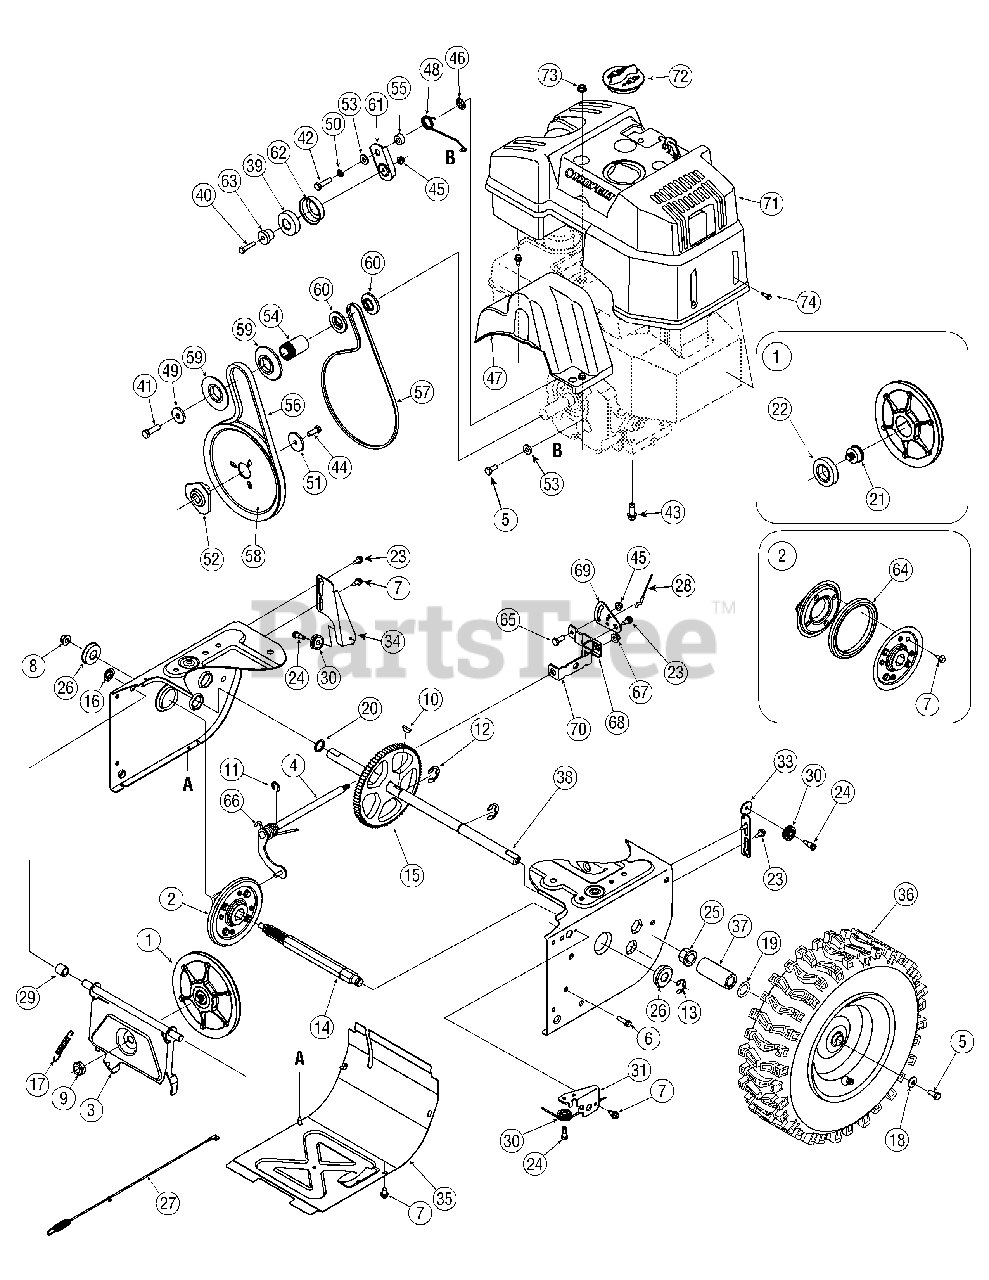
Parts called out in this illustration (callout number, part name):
1	Disc Assembly, Friction Wheel
2	Friction Wheel Assembly, 5.5 OD
4	Shift Assembly, Rod
5	Hex Screw, 5/16-24, .750, Gr5
6	Screw, 1/4-20, 1.000
7	Screw, 1/4-14 x .625
8	Nut, Flange Lock, 3/8-16, Nylon
9	Nut, Jam Lock, 5/8-18, Gr5, Nylon
10	Key, Hi Pro, 3/16 x 3/4 Dia.
11	E-ring, .500 Dia.
12	E-ring, Retaining, .875 Dia.
13	E-ring, .750 Dia.
14	Hex Shaft, .8125, 7-Tooth
15	Gear, 80-Tooth
16	Speed Nut, .500
17	Extension Spring
18	Washer, Bell, .340 x .872 x .060
19	Washer, Flat, .793 x 1.24 x .060
20	Washer, Flat, .75 x 1.00 x .060
21	Pin, Friction Disc
22	Ball Bearing, 30 x 55 x 13
23	Screw, Shoulder, .37 x .105, 1/4-20
24	Screw, 1/4-28, .375
25	Bearing, Hex Flange x .75 ID
26	Bearing, Ball, 17 x 40 x 12
27	Clutch Cable, Wheel, 44.95"
28	Cable, Speed Selector
29	Spacer, .508 ID x .75 OD x .68
30	Roller, Cable
37	Spacer, 1.25 x .75 x 3.0
38	Axle, .75 x 22"
39	Ball Bearing
40	Hex Screw, 1/4-20, 1.25, Gr5
41	Hex Screw, 3/8-24, 1.25, Gr8
42	Hex Screw, 5/16-24, 1.25, Gr5
43	Screw, Sems, 3/8-16, 1.00
44	Hex Screw, 5/16-24, .875, Gr8
45	Nut, Flange Lock, 1/4-20, Nylon
46	Nut, Push-on, .25 Dia.
47	Cover, Belt
48	Spring, Torsion, .850 ID x .354
49	Washer, Flat, .406 x 1.25 x .157
50	Washer, Lock .3125
51	Washer, Flat, .34 x 1.50 x .150
52	Pulley, Adapter, .75 Dia.
53	Spacer, Shoulder, .317 x .50 x .102
54	Spacer, .875 ID x 1.185 OD
55	Spacer, .340 x .750 x .360
56	Belt, Auger Drive
57	Belt, Wheel Drive
58	Pulley, Auger Drive, 8.1 x .5
59	Pulley, Half, V x 2.600 OD
60	Pulley, Half, 1/4-V x 1.5 OD
61	Idler Bracket, Wheel Drive
62	Sleeve, Bearing Idler
63	Spacer, Shoulder, .26 x .79 x .538
64	Rubber, Friction Wheel, 5.5 OD
65	Hex Screw, 1/4-20, .620, Gr5
66	Spring, Torsion, .750 ID x .968
67	Nut, Flange Lock, 5/16-18, Nylon
68	Bracket, Shift Spacer
71	Engine Shroud, Troy-Bilt
72	Cap, Spark Plug Access
73	Nut, Flange Lock, 5/16-18, GR5
74	Screw, #10-16, .75
